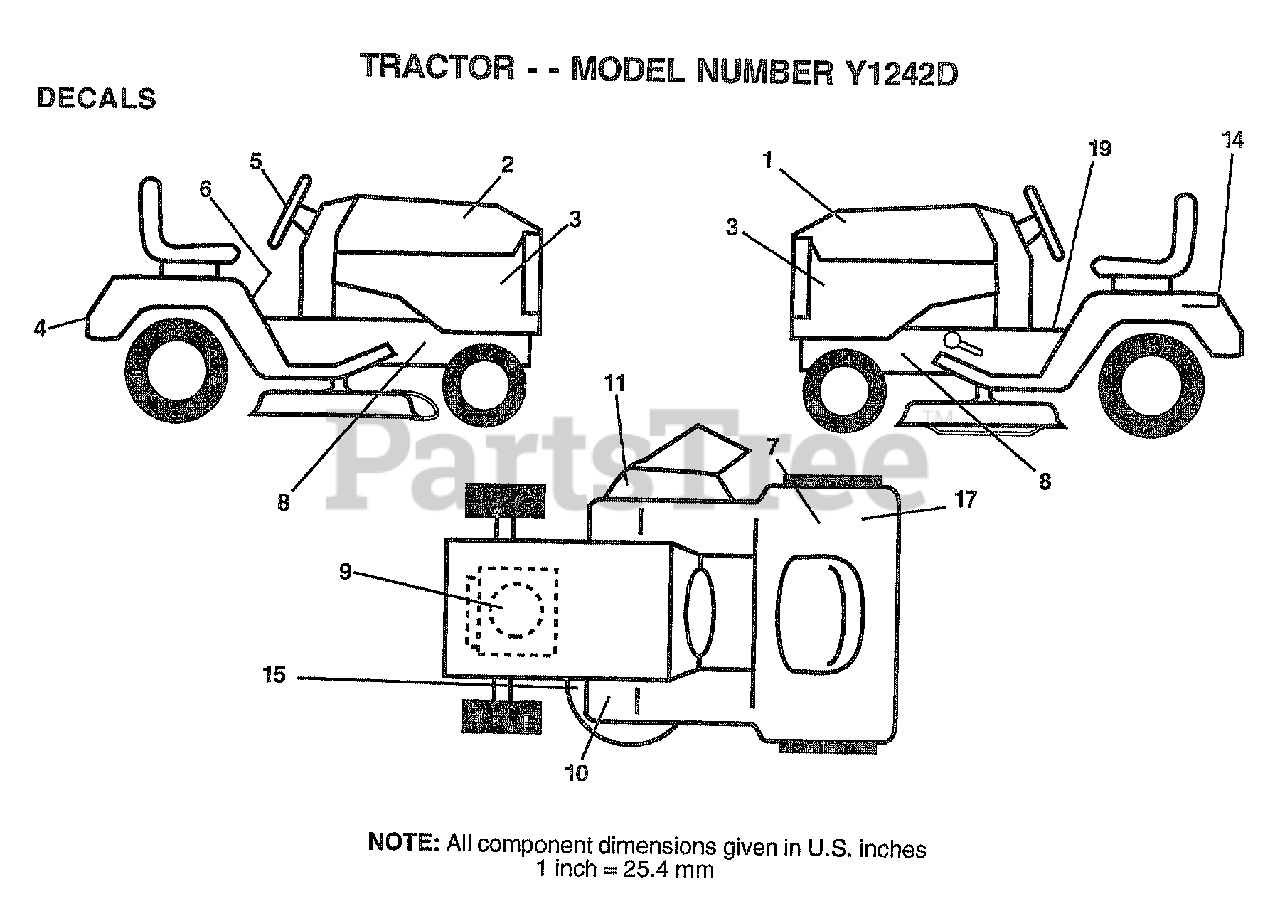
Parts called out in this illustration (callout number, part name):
1	DECAL.HD.LH.
2	DECAL.HD.RH.
3	"DECAL PANEL,SIDE"
5	DECAL.INS.STRG.WH
6	DECAL.READ.O.MANU
7	DECAL.EURO.ST.CE.
8	"DECAL CHASSIS,HOT"
9	DECAL, ENGINE
10	DECAL-BRAKE/CLUTC
11	DECAL.DANGER.CUTF
14	DECAL.BATRY.3-3908
15	"DECAL-SCHEM,BELT"
19	DECAL BRAK PARK
